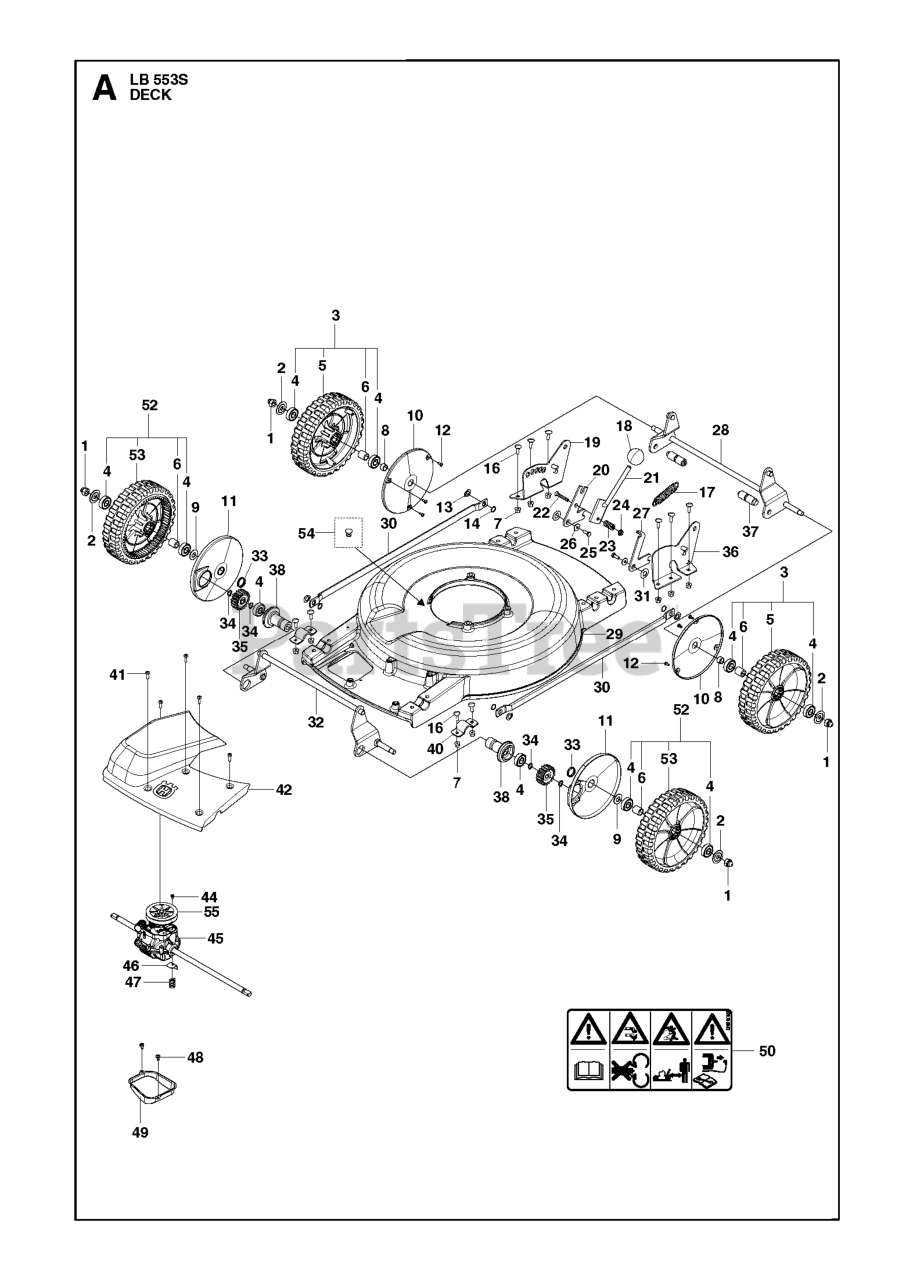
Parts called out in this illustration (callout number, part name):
1	NUT M53S / M48S
3	WHEEL PRO HUSQVARNA
4	BALL BEARING 6201-2RS/C3 W10
5	WHEEL ASSY PRO HUSQVARNA
6	SPACER PRO
7	LOCKING NUT FLANGE
8	SPACER M53 L=14
9	SPACER WASHER M53S / M48S
10	SHIELD PRO
13	RING M53S / M48S
14	RETAINING RING
17	SPRING M53 / M48
18	BALL M53 / M48
21	LEVER ASSY M53 / M48 M53
23	SPRING M53 / M48
24	FLANGE NUT
25	BOLT FLANGE M6X16
28	AXLE ASSY M53 PRO
29	CHASSIS M53S HUSQVARNA WITH CR
33	SPRING M53 / M48
35	PINION PRO
44	SCREW RXS B8X9.5
46	BRACKET M53 / M48
47	SPRING M53S / M48S
48	SCREW ITXPANTT M5X10 ZPB (A00
49	CUP PRO
52	WHEEL PRO, DRIVING HUSQVARNA
53	WHEEL ASSY PRO, DRIVING HUSQVA
